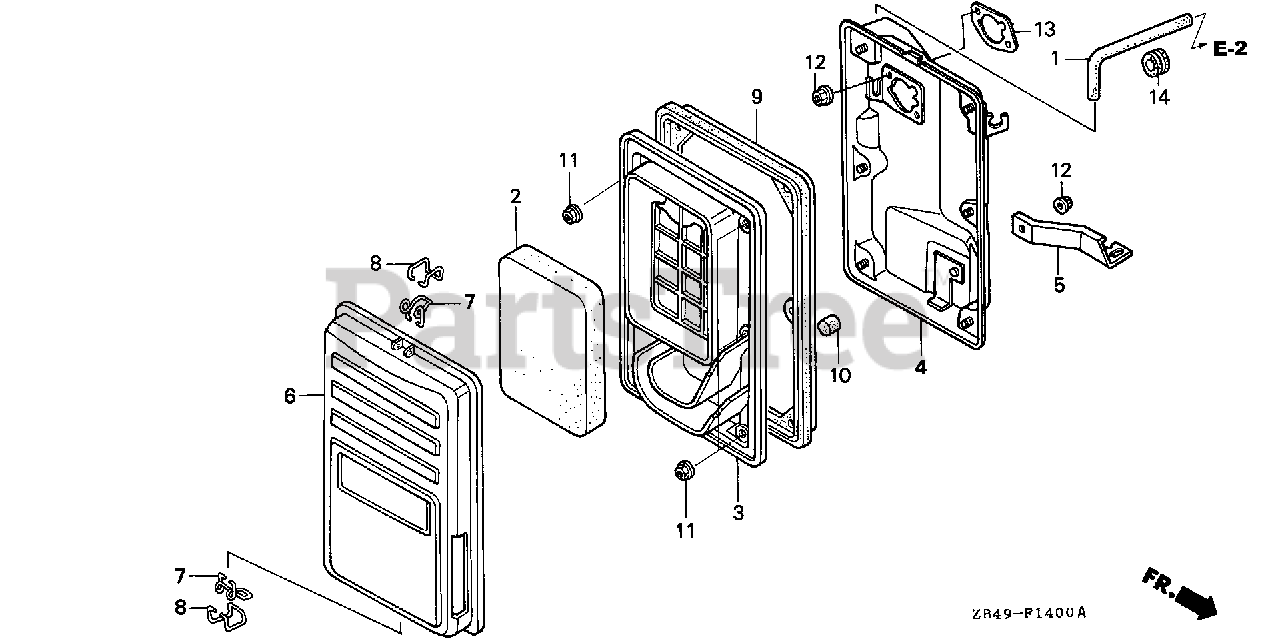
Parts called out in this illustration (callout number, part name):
1	TUBE, BREATHER
2	ELEMENT, AIR CLEANER
3	SEPARATOR, AIR CLEANER
4	HOUSING, AIR CLEANER
5	STAY, AIR CLEANER
6	COVER, AIR CLEANER
7	CLIP A, AIR CLEANER WIRE
8	CLIP B, AIR CLEANER WIRE
9	SEAL, AIR CLEANER
10	FILTER, DRAIN TUBE
11	NUT, FLANGE (5MM)
12	NUT, FLANGE (6MM)
13	GASKET, AIR CLEANER
14	GROMMET, FENDER
